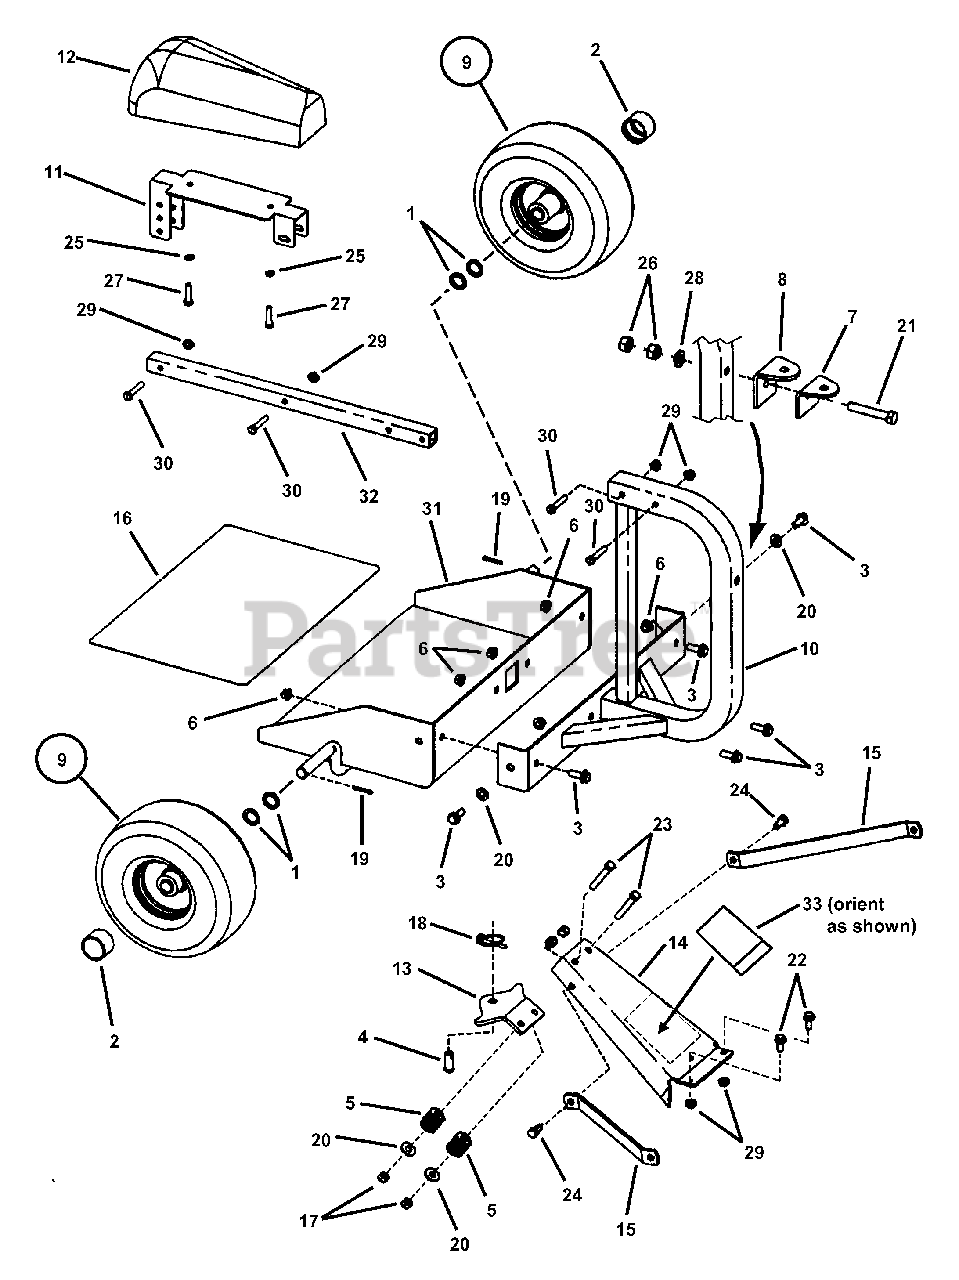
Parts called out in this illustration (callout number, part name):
1	WASHER, 3/4" Flat
2	CAP, Hub
3	BOLT, 3/8-16 x 1 ", Grade 5
4	PIN, 1/2 x 1-3/16" Clevis
5	SPRING (2)
6	NUT, 3/8-16 Hex Flange Lock
7	HITCH, Bottom
8	HITCH, Top
9	ASSEMBLY, Tire & Rim
10	WELDMENT, Seat Support
11	BRACKET, Seat
12	SEAT
13	HITCH, Draw Bar
14	DRAW BAR
15	BRACE, Draw Bar
16	PAD, Friction
17	NUT, 3/8-16 Hex Nyloc
18	PIN, 7/16 HD Lynch
19	PIN, 5/32 x 1" Cotter
20	WASHER, 3/8" Flat
21	SCREW, 1/2-13 x 3" Hex Head Cap, Grade 5
22	BOLT, 5/16-18 x .5/8" Hex Flange Lock, Grade 5
23	SCREW, 3/8-16 x 2-1/4" Hex Head Cap, Grade 5
24	SCREW, 3/8-16 x 1" Hex Head Cap, Grade 5
25	WASHER, 21/64" Split Lock
26	NUT, 1/2-13 Hex Grade 5
27	SCREW, 5/16-18 x 1-1/4" Hex Head Cap, Grade 5
28	WASHER, 17/32" Flat
29	NUT 5/16-18 Hex Flange Lock, Grade 5
30	SCREW, 5/16-18 x 1.3/4", Grade 5
31	WELDMENT, Carriage/Axle
32	TUBE, Seat Extension
33	DECAL, Warning
